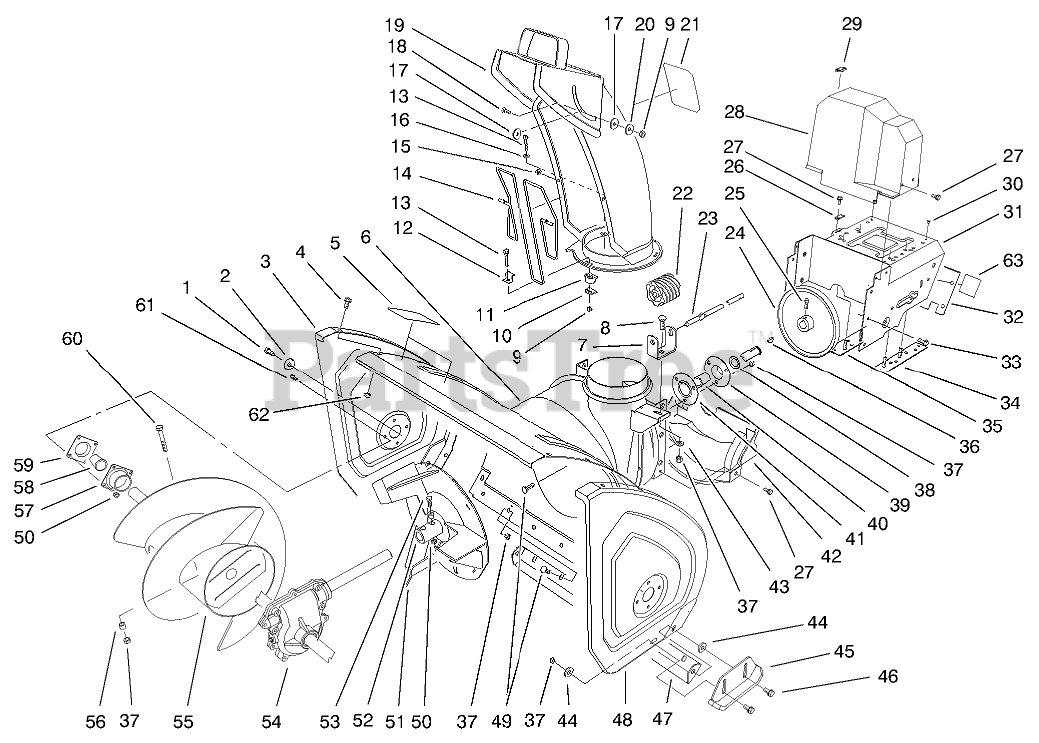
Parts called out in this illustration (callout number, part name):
1	SCREW-HH
2	WASHER
3	PLATE-SIDE, RH
4	SCREW-HHF
6	Auger Housing ASM (only on: 38087)
6	Auger Housing ASM (only on: 38592)
6:2	Decal-Warning, Auger (only on: 38592)
6:2	Decal-Warning, Auger (only on: 38087)
7	BRACKET-WORM, CHUTE
8	BOLT-CARR
9	NUT-LOCK, NI
10	PLATE-RETAINER, CHUTE
11	RETAINER-CHUTE
12	CLIP-GUARD, CHUTE
13	SCREW-HSH
14	GUARD-CHUTE
15	NUT-PUSH
16	WASHER-FLAT
17	WASHER-PLASTIC
19	Chute (only on: 38592)
19	Chute (only on: 38087)
19:2	Decal-Danger Discharge (only on: 38087)
19:2	Decal-Danger (only on: 38592)
20	WASHER-FLAT
22	GEAR-WORM
23	ROD-CHUTE, LOWER
24	PULLEY-IMPELLER
25	SCREW-SET, SQH
26	RETAINER-CABLE
27	SCREW-HWH
28	COVER-BELT, UPPER
29	COVER-CABLE
30	RIVET-POP
31	Engine Frame ASM (only on: 38087)
31	Engine Frame ASM (only on: 38592)
31:2	Decal-Warning (only on: 38592)
31:2	Decal-Adjustment (only on: 38087)
32	COVER-FRAME, ENGINE
33	SCREW-HWHTF
34	LH FRAME PLATE ASM
35	RH FRAME PLATE ASM
36	KEY-WOODRUFF
37	NUT-LOCK, NI
38	WASHER-THRUST
39	FLANGE-CUP, BEARING
40	BEARING-BALL
41	FLANGE-CUP, BEARING
42	COVER-BELT, LOWER
43	WASHER-PLAIN
44	WASHER
45	SKID ASM
46	SCREW-HHF
47	BLADE-SCRAPER
48	PLATE-SIDE, LH
49	SCREW-CARR
50	NUT-LOCK, NI
51	IMPELLER-4 BLADE
52	SPACER
53	SCREW-HHF
54	LH AUGER GEARCASE ASM
55	AUGER, RH
56	SPACER-HUB, AUGER
57	BEARING-FLANGE, FRONT
58	BEARING
59	BEARING-FLANGE, REAR
60	SCREW-HH
61	SCREW-HH
62	NUT-LOCK, NI
63	Decal (only on: 38592)
